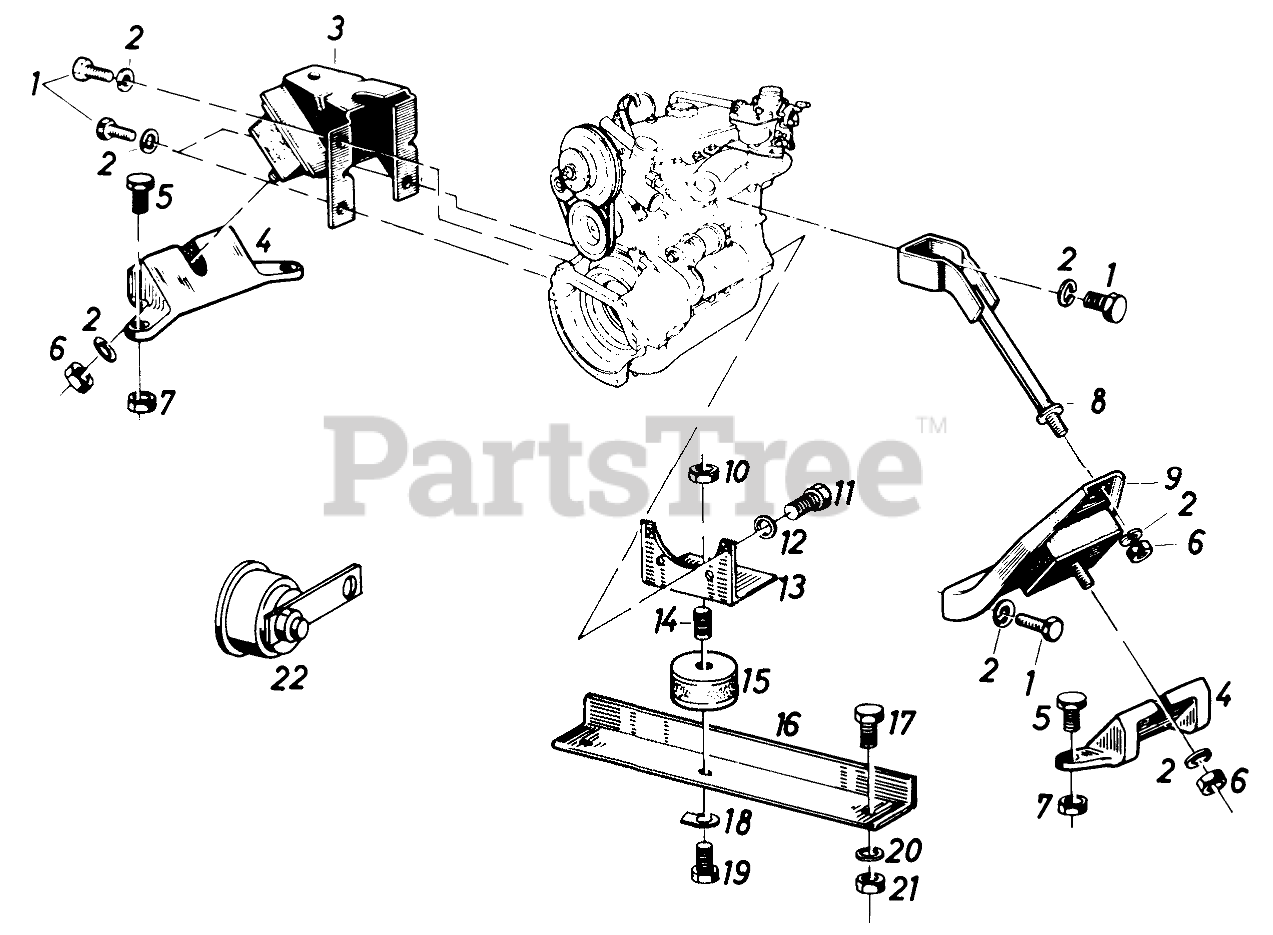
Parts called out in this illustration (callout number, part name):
2	Lockwasher
3	Motor Support Right
4	Motor Support
8	Support
9	Motor Support Left
11	Screw
12	Schnorr Washer
13	Bracket
15	Mount Vibration
16	Support
17	Screw
18	Lock Washer
20	Washer
